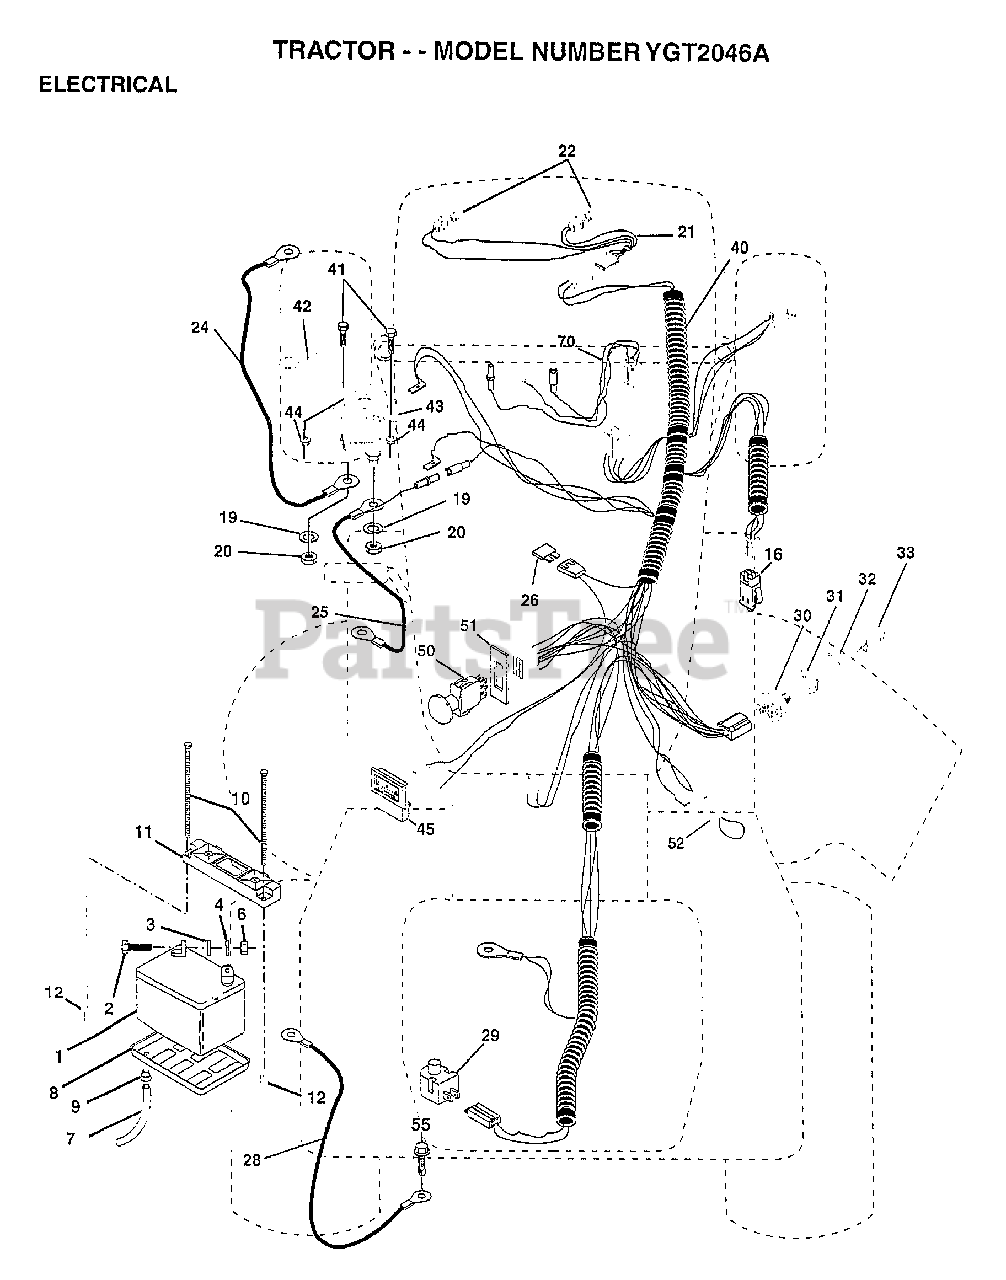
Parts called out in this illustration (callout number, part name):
2	BOLT LT
3	WASHER
4	LOCKWASHER
7	"DRAIN TU T, BATT"
8	"TRAY T, BATTERY"
9	HOSE CLAMP T
11	HOLDDOWN BATTERY
16	SWITCH INTERLOCK
20	NUT
21	HARNESS.ASM.HDLIG
22	HEADLAMP BULB
24	CABLE.BTRY.6GA.RD
25	CABLE.6GA.22W/16W
26	FUSE HYT
28	CABLE.GRND.6GA.21
29	SWITCH SEAT
30	SWITCH IGN 4POS
31	NUT IGNITION
32	COVER KEY SWITCH
33	KEY
40	HARNESS IGNITION
41	BOLT HXHD FIN
44	NUT HXKEP 1/4X20
45	AMMETER
50	PTO SWITCH.BLK
51	RING RETAIN PTO
52	PROTECTION LOOP
55	SCREW LT
70	HARNESS ENGINE
